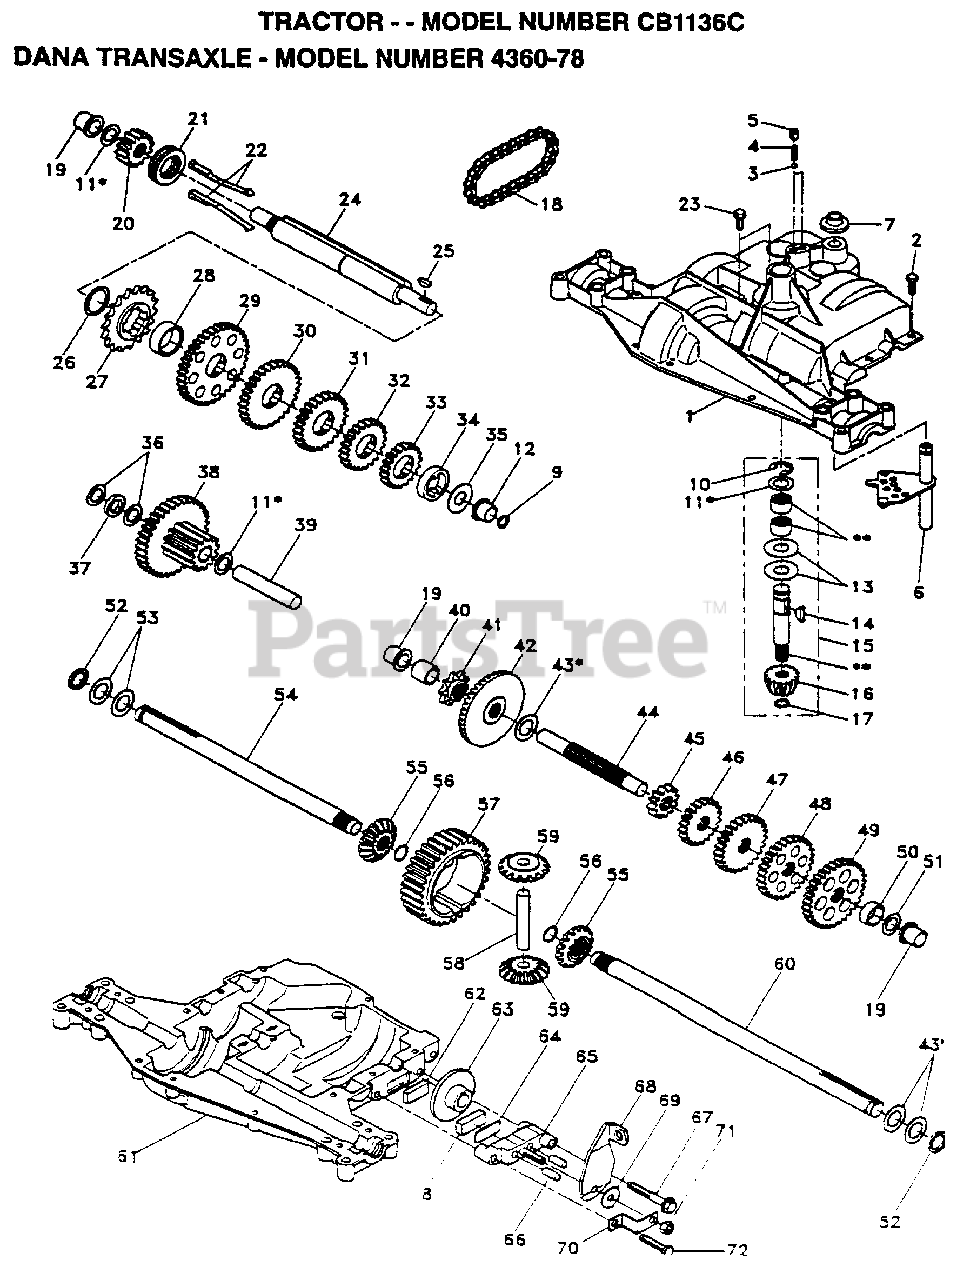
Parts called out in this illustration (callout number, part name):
1	HOUSING UPPER TRN
4	"SPRING, DETENT LT"
5	"SCREW, SET LT"
6	KIT SHIFTER ASM
7	SHIFTER BOOT
8	PUCK T
9	SEAL OIL DANA5416
11	ASM KIT SHIM 4689
13	WASHER T
14	KEY WOODRUFF-DANA
15	AS KIT INPUT SHFT
16	PINION 14T T
17	"RING,RETAINING LT"
18	"CHAIN,24 PTCH LT"
19	BEARING.FLNG.5510
20	GEAR SPUR 14 TTH
21	COLLAR CLUTCH
22	ASM KIT CLTCH KEY
23	SCREW TAP W/SEAL
24	SHAFT INTERM DANA
25	WOODRUFF KEY
26	"RING,RETAINING LT"
27	SPROCKET 18T T
28	SPACER YT
29	GEAR SPUR 37 TTH
31	GEAR 25T LT
32	GEAR SPUR 22 TT
33	SPUR GEAR 19T
34	SPACER
35	"WASHER, PLAIN LT"
36	WASHER 025
37	SPACER
38	ASSM GEAR COMB
39	SHAFT IDLER
40	SPACER T
41	SPROCKET 9T LT
43	ASM KIT SHIM
44	SHAFT T
45	GEAR SPUR 12 TTH
47	"GEAR, SPUR 25T LT"
48	GEAR 28T T
49	"GEAR, SPUR 31T LT"
51	WASHER 060
52	NEOPRENE WASHER
53	WASHER 031
55	GEAR 15T T
56	"RING,RETAINING LT"
58	SHAFT T
59	GEAR 1ST T
61	HOUSING LOWER TNS
62	PUCK T
63	BRAKE DISC. T
64	SPACER LT
66	PIN T
69	WASHER LT
71	NUT.LOCK.5/16-24
72	"SCREW, TAPPING LT"
